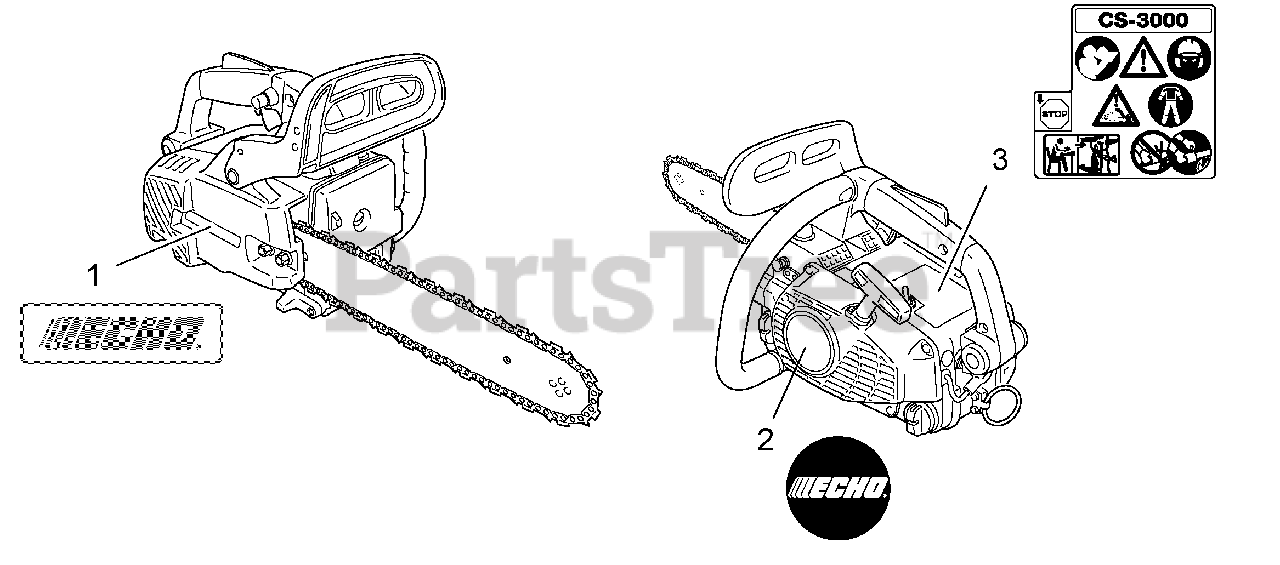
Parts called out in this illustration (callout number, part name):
1	LABEL - ECHO
2	LABEL - ECHO
3	LABEL - MODEL CS-3000
